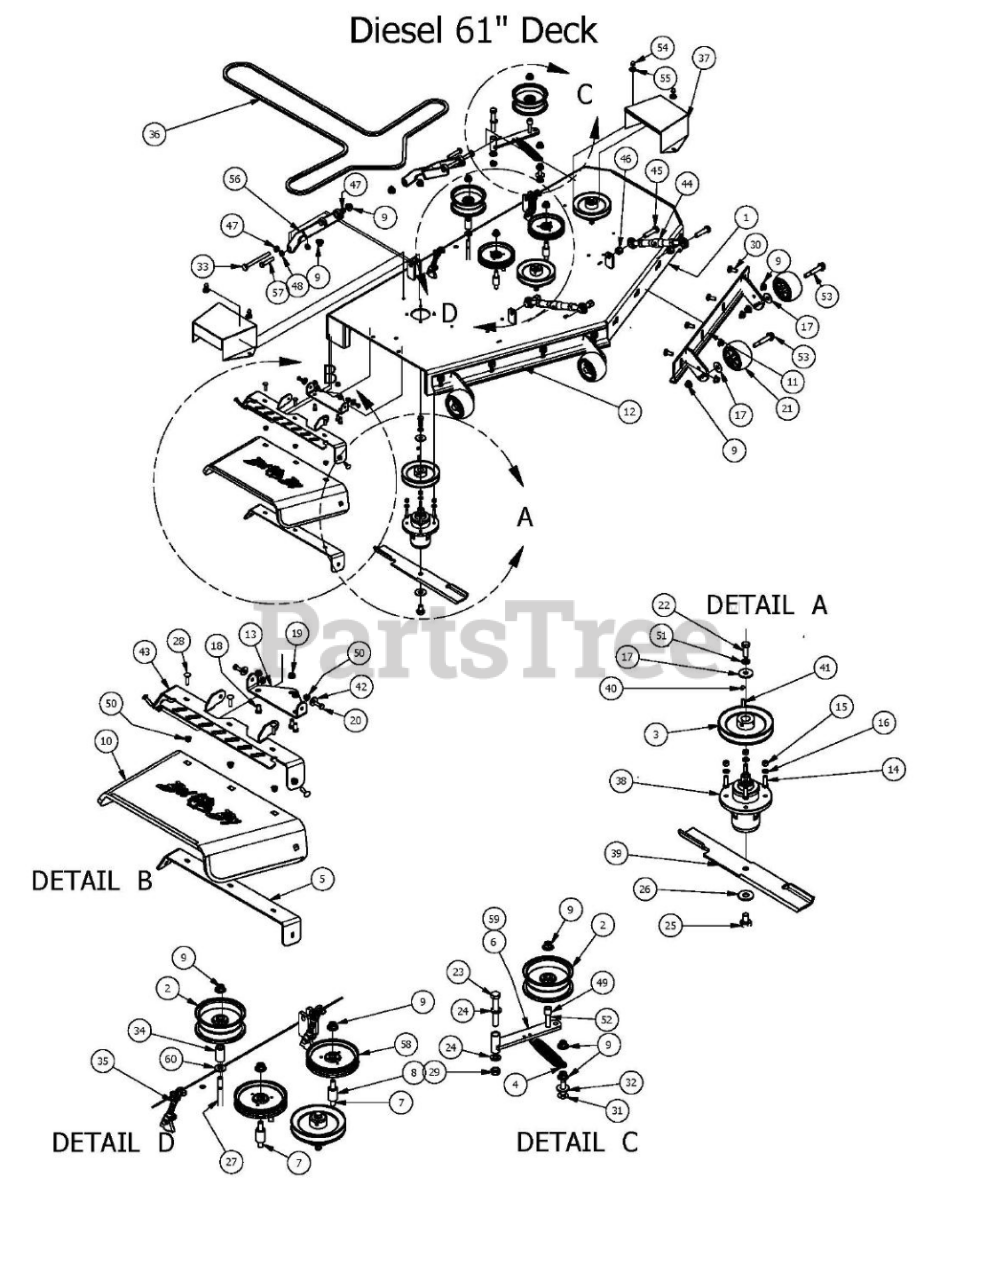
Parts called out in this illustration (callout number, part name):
1	61" AOS Deck
2	5 3/4" Deck Idler Pulley
3	6 1/4" Drive Pulley
4	2015 Deck Idler Spring
5	60" Discharge Lower Bracket
6	Deck Idler
7	1/2 x 3 1/2 Flange Bolt Grade 8
8	Idler Pulley Standoff
9	1/2-13 Nylon Insert Flange Nut
10	Rubber Discharge Chute
11	61 Outlaw Adjustable Deck Front (Left)
12	61 Outlaw Adjustable Deck Front (Right)
13	Discharge Chute Hanger (deck mounted)
14	3/8" x 1 1/4" Hex Bolt
15	3/8-16 Hex Nuts Zinc
16	3/8 Lockwasher Zinc
17	1/2" Belleville Washer
18	3/8" x 3/4" Hex Bolt
19	3/8" Flange Nut
20	5/16" x 1" Bolt
21	Anti-Scalp Roller
22	1/2"-20 x 1 1/2 - Grade 5 Fine Thread Bolt
23	5/8" x 4" Hex Bolt
24	.630 ID Plastic Washer
25	5/8" x 1 1/2" Grade 8 Hex Bolt (Fine)
26	5/8" Flat Washer
27	1/2" x 4" Bolt (Grade 8)
28	5/16" x 1 1/4" Carriage Bolt
29	5/8-11 Nylon Insert Jam Half Nut
30	1/2" x 1 1/4 Carriage Bolt
31	1/2 x 2" Carriage Bolt
32	.517 Square Hole Round Washer
33	1/2" x 5 1/2" Bolt
34	1 3/4" Pulley Spacer
35	4-Link Adjustable Deck Hange
36	B236 Belt Diesel EZ Ride
37	Pulley Cover
38	Double Bearing Spindle
39	61 inch Fusion Blade
40	5/16 Set Screw
41	1/4" x 1" Key
42	.360 ID Plastic Washer
43	60" Discharge Chute Upper Hanger
44	Turnbuckle (Top Link)
45	5/8" x 2 1/2" Grade 5 Hex Bolt (Coarse)
46	5/8 Std NC Nylock Nut
47	Flange Bushing For Upper Deck Arm
48	Flange Bushing For Lower Deck Arm
49	Spacer 3/4 OD x 1/2 ID x 314 Length
50	5/16" Nylon Flange Nut
51	1/2" Lock Washer
52	1/2-13 x GR 5 Hex Bolt Zinc
53	Deck Wheel Bolt
54	Acorn nut-pulley Cover
55	.360 ID Plastic Washer-Black
56	Deck Arm Assembly
57	1/2" x 3" Hex Bolt
58	5-3/4 Idler Pulley-Capitol Stampings
59	Deck Idler Assembly-parts of Assembly 2,6,9,49,52
60	1/2" Washer (Grade 8)
